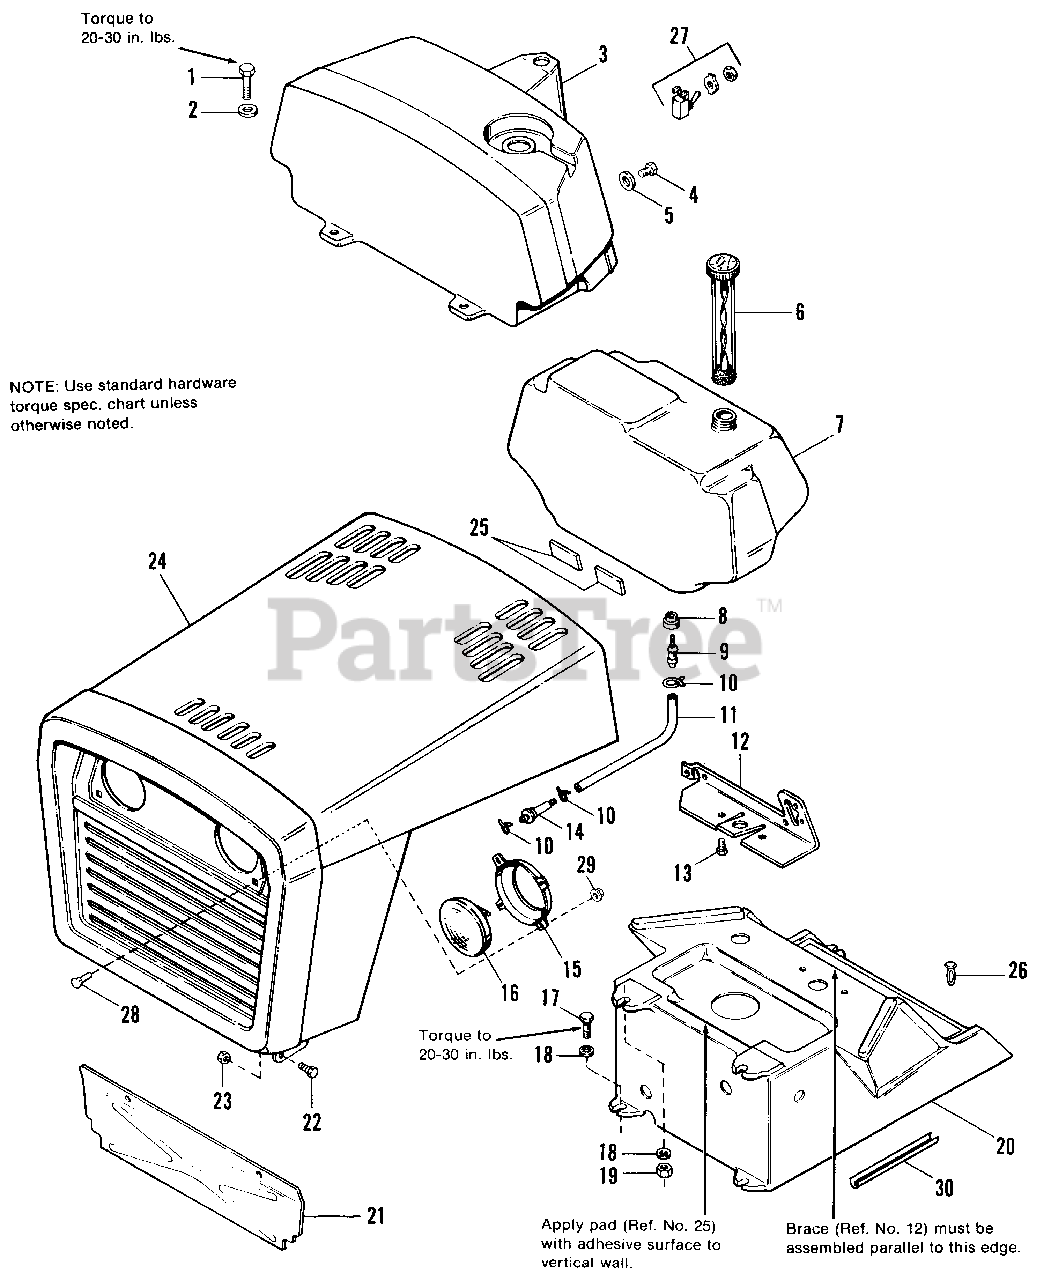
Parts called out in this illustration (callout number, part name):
1	CAPSCREW, Hex Hd., 1/4-20 x 1-1/4
2	WASHER, Plain, 1/4
3	DASH BOARD, Top
4	SCREW, #14 x 3/4
5	WASHER, Plain, 3/16
7	TANK ASSY., Fuel
10	CLAMP, Hose
12	BRACE, Dash
13	SCREW, Hex, Taptite, 1/4-20 x 1
14	FILTER, Fuel
15	BRACKET, Support, Headlight
16	LAMP, Sealed Beam, G.E., #4411-1
17	SCREW, Hex, Taptite, 1/4-20 x 1
18	LOCKWASHER, Dished Type, 1/4
19	LOCKNUT, Hex, 1/4-20
20	DASH, Board, Bottom
21	BAFFLE, Engine, Front
22	CAPSCREW, Hex Hd., 3/8-16 x 7/8
23	LOCKNUT, Hex, 3/8-16
24	HOOD & GRILLE ASSY.
26	CLIP, Canoe
27	SWITCH, Toggle
28	BOLT, Carriage, #10-24 x 5
29	PAL NUT, #10-24
30	EDGING, Lower Dash
